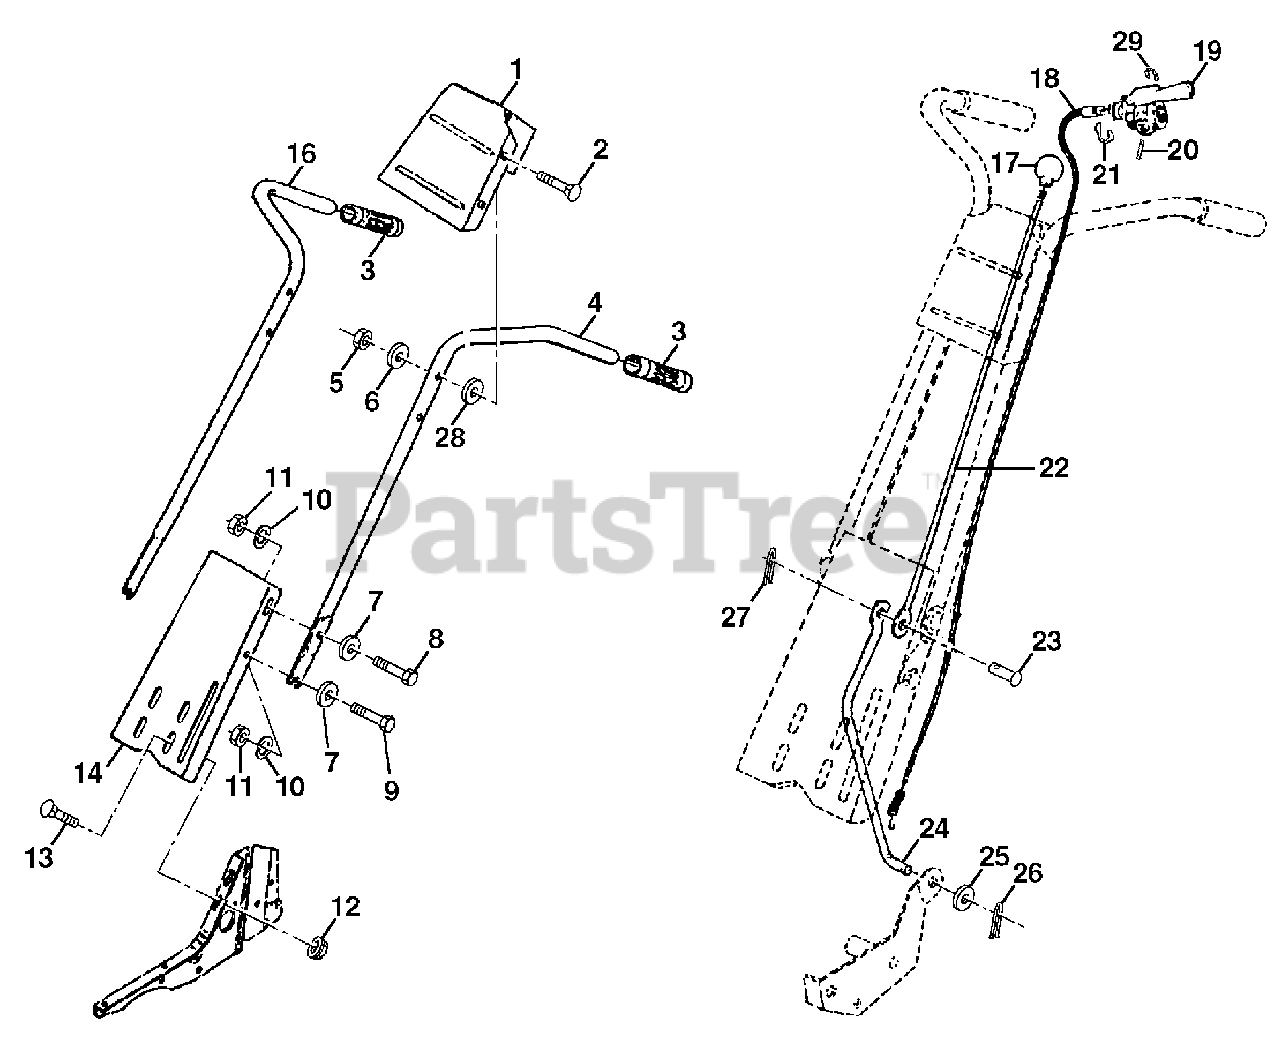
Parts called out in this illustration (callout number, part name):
1	Bracket, Handle
2	Bolt, Carriage 5/16-18 UNC x 1-1/2
3	Grip, Handle
4	Handle, L.H.
5	Locknut, Crown 5/16-18
6	Washer 11/32 x 11/16 x 16 Ga.
7	Washer 3/8 x 7/8 x 14 Ga.
8	Bolt, Hex Hd 5/16-18 x 1
9	Bolt, Hex Hd 5/16-18 x 3/4
10	Washer, Lock 5/16
11	Nut, Hex 5/16-18
12	Nut, Flanged 5/16-18
13	Bolt, Carriage 5/16-18 x 3/4 Gr. 5
14	Panel, Handle
16	Handle, R.H.
17	Knob, Control, Reverse
18	Cable, Control, Tine
19	Control, Tine
20	Pin, Pivot
21	Ring, Klip
22	Rod, Reverse, Upper
23	Pin, Retaining
24	Rod, Reverse, Lower
25	Washer 13/32 x 13/16 x 16 Ga.
26	Pin, Cotter 1/8 x 3/4
27	Pin, Cotter 3/32 x 1/2
28	Washer 13/32 x 13/16 x 12 Ga.
29	Retaining, Ring
